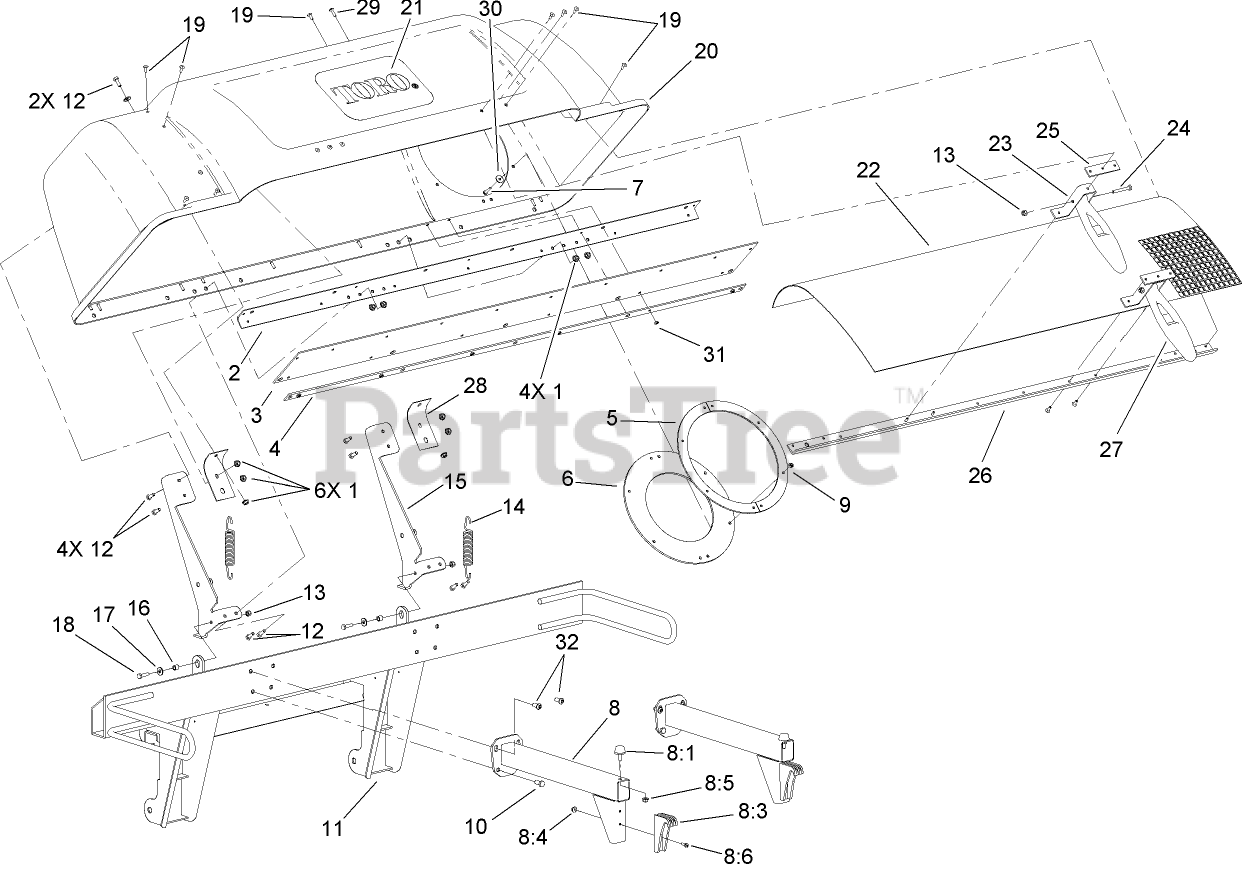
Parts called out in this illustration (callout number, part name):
1	NUT-HF
2	Stiffener-Bagger, Top
3	Seal-Hinge
4	Plate-Backing
5	CLAMP-SEAL
6	SEAL-TUBE
7	SCREW-PPH
8	BAG SUPPORT ASM
8:1	BUMPER
8:4	NUT-HF
8:5	NUT-HF
8:6	SCREW-PPH
9	NUT-LOCK, NI
10	SCREW-HH
11	UPRIGHT BAGGER ASM
12	SCREW-HH
13	NUT-LOCK, NI
14	SPRING-EXTENSION
15	HINGE ASM
16	SPACER
17	WASHER-FLAT
18	SCREW-HH
19	RIVET-BLIND
20	HOOD ASM
21	DECAL
22	Screen-Bagger
23	Bracket-Mount
24	SCREW-HH
25	Plate-Latch, Reinforcement
26	Support-Screen
28	Reinforcement-Hood, Bagger
29	SCREW-HEAD, TRUSS
30	WASHER-FLAT
31	NUT-LOCK, SIDE
32	SCREW-HSBH
